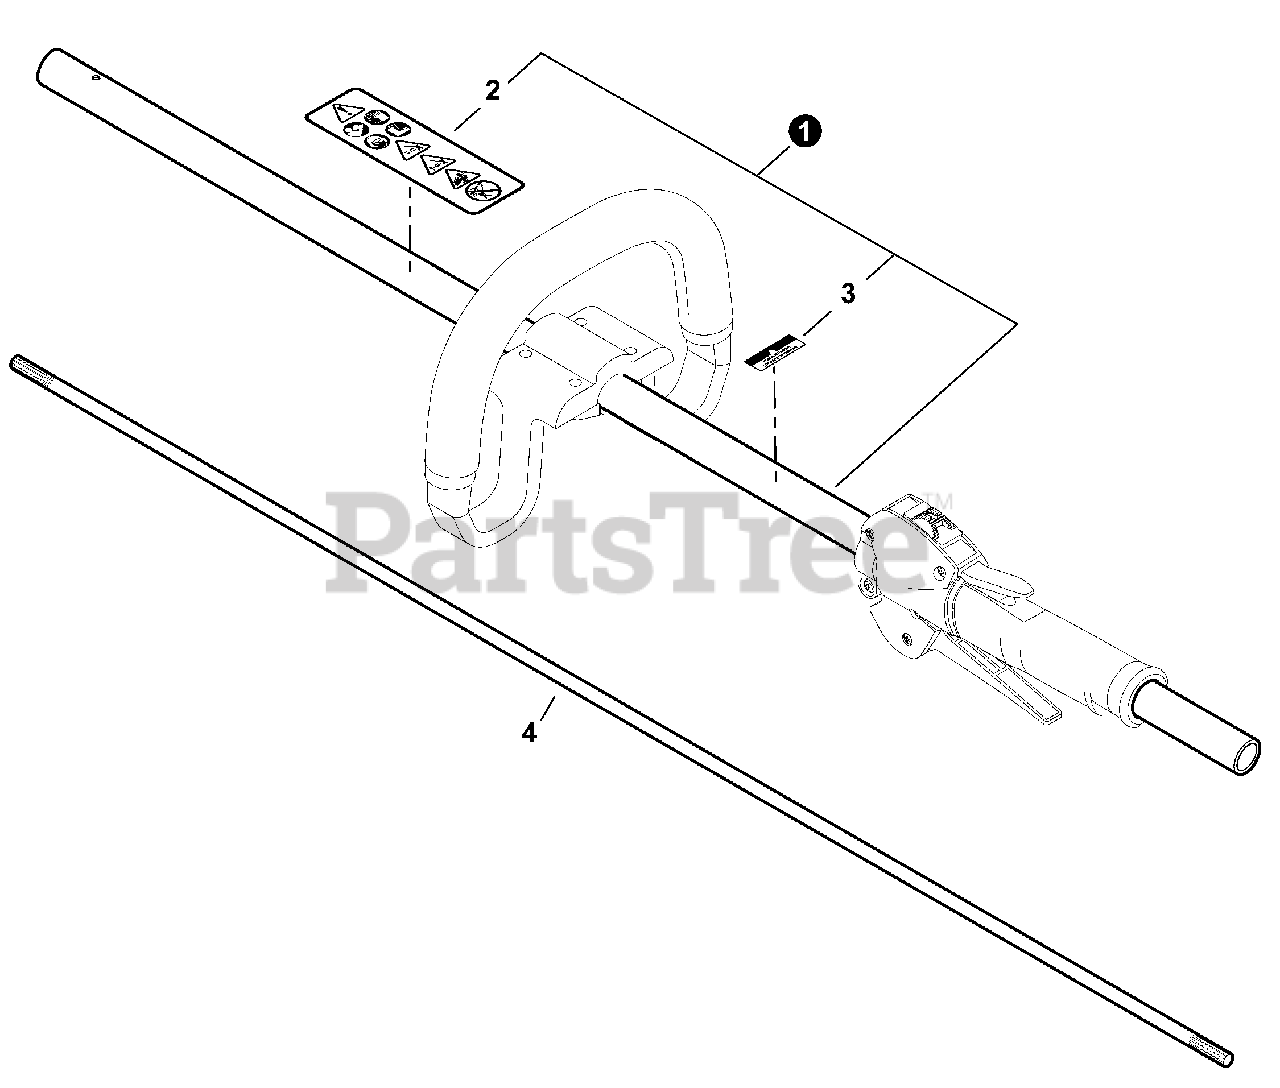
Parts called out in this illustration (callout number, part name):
1	MAIN PIPE ASSY
2	LABEL, CAUTION
3	LABEL, HANDLE
4	MAINSHAFT
